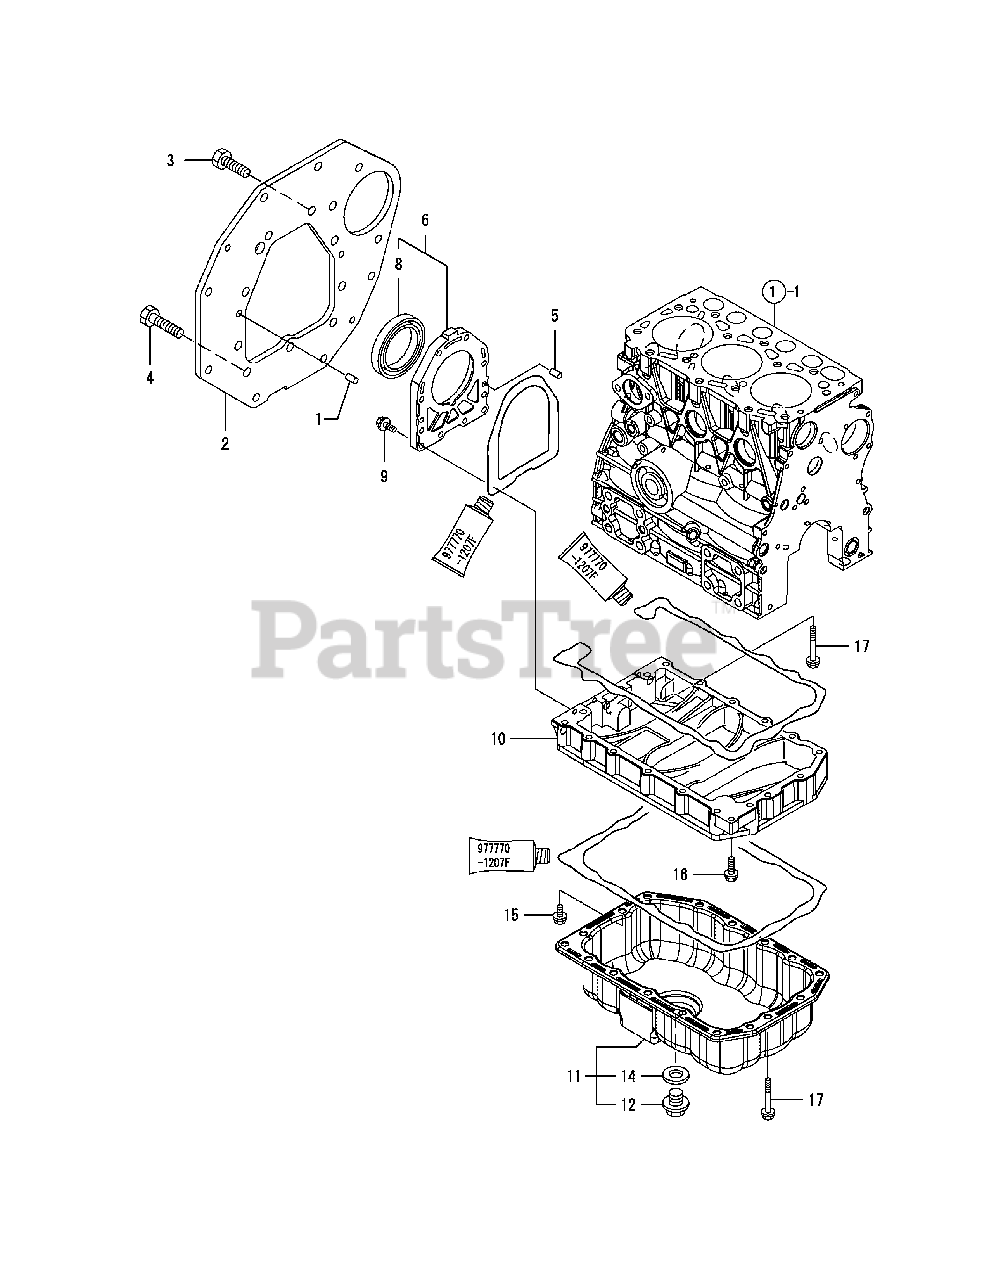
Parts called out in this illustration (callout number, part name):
1	Parallel Pin, 8 x 16
2	Flange, Mounting
3	Bolt, M10 x 20
4	Bolt, M10 x 25
5	Parallel Pin, 6 x 10
6	Case Assembly, Oil Seal
9	Bolt, M 6 x 22 Plated
10	Spacer, Oil Sump
11	Sump Assembly, Lub. Oil
14	Seal, Washer, 16S
15	Bolt, M 6 x 12 Plated
16	Bolt, M 6 x 25 Plated
17	Bolt, M 6 x 45 Plated
